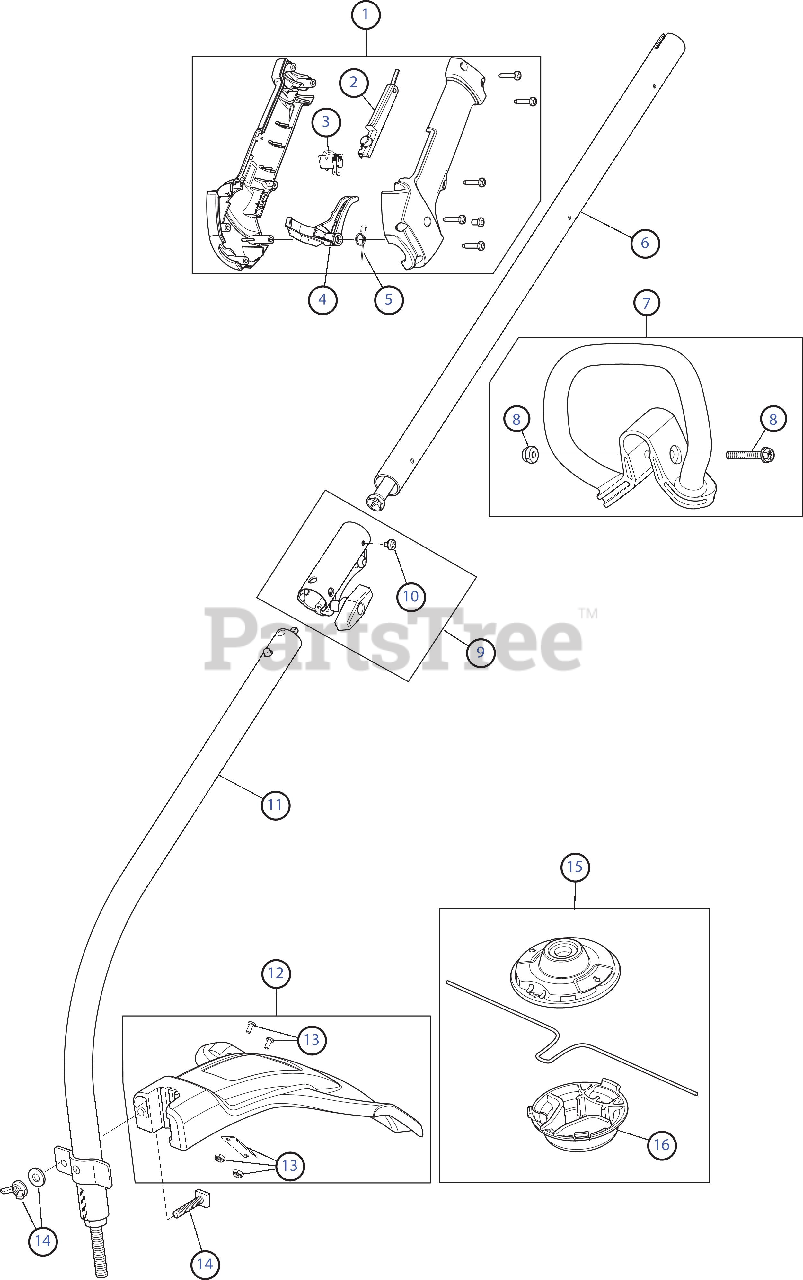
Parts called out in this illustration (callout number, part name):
1	Throttle Housing Assembly (Incl. 2 - 5)
2	Throttle Trigger Lock-Out
3	Trigger Switch Assembly
4	Throttle Trigger
5	Throttle Trigger Spring
6	Upper Shaft Housing Assembly
7	D-Handle (Incl. 8)
8	D-Handle Bolt
9	Split Boom Coupler Assembly (Incl. 10)
10	Anti-Rotation Screw
11	Lower Shaft Housing Assembly
12	Shield Assembly (Incl. 13)
13	Blade Assembly
14	Shield Mounting Hardware
15	Cutting Head Assembly (Incl. 16)
16	Glide Cap
